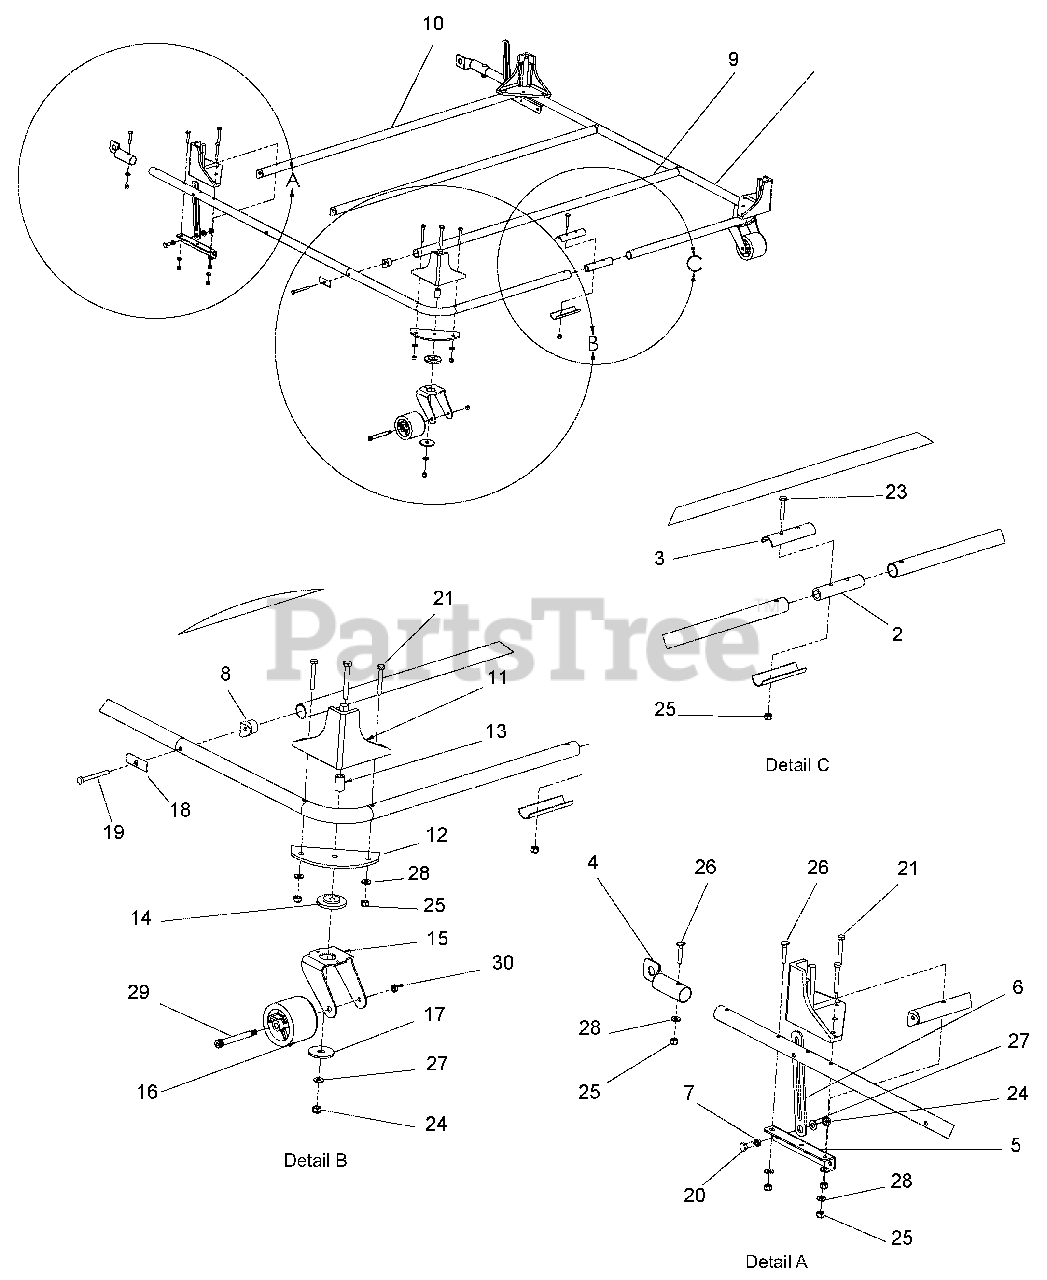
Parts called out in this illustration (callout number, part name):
1	Frame Side
2	Tube Insert
3	Clamp Half
4	End Cap, Tube
5	Angle Bracket
6	Bracket, Adjust
8	Tube Connector
9	Cross Brace, Mid/Back
10	Cross Brace, Forward
11	Corner Support
12	Caster Plate
15	Caster Fork
18	Bracket Clamp
19	Bolt, 1/4-20 x 2.50 Hex 5
20	Bolt, 5/16-18 x .75 Hex 5
21	Bolt, 1/4-20 x 2.00 Hex 5
22	Bolt, 5/16-18 x 2.50 Hex 5
23	Bolt, 1/4-20 x 1.50 Hex 5
24	Nut, 5/16-18 Nyloc
25	Nut, 1/4-20 Nyloc
26	Bolt, 1/4-20 x 1.50 Contour Hd.
27	Washer, .344 x .688 x .065 Flat Steel
28	Washer, .281 x .62 x .065 Flat Steel
29	Bolt, .38 x 2.75 x .31-18 Shoulder Socket
30	Nut, 1/4-20 Lock
